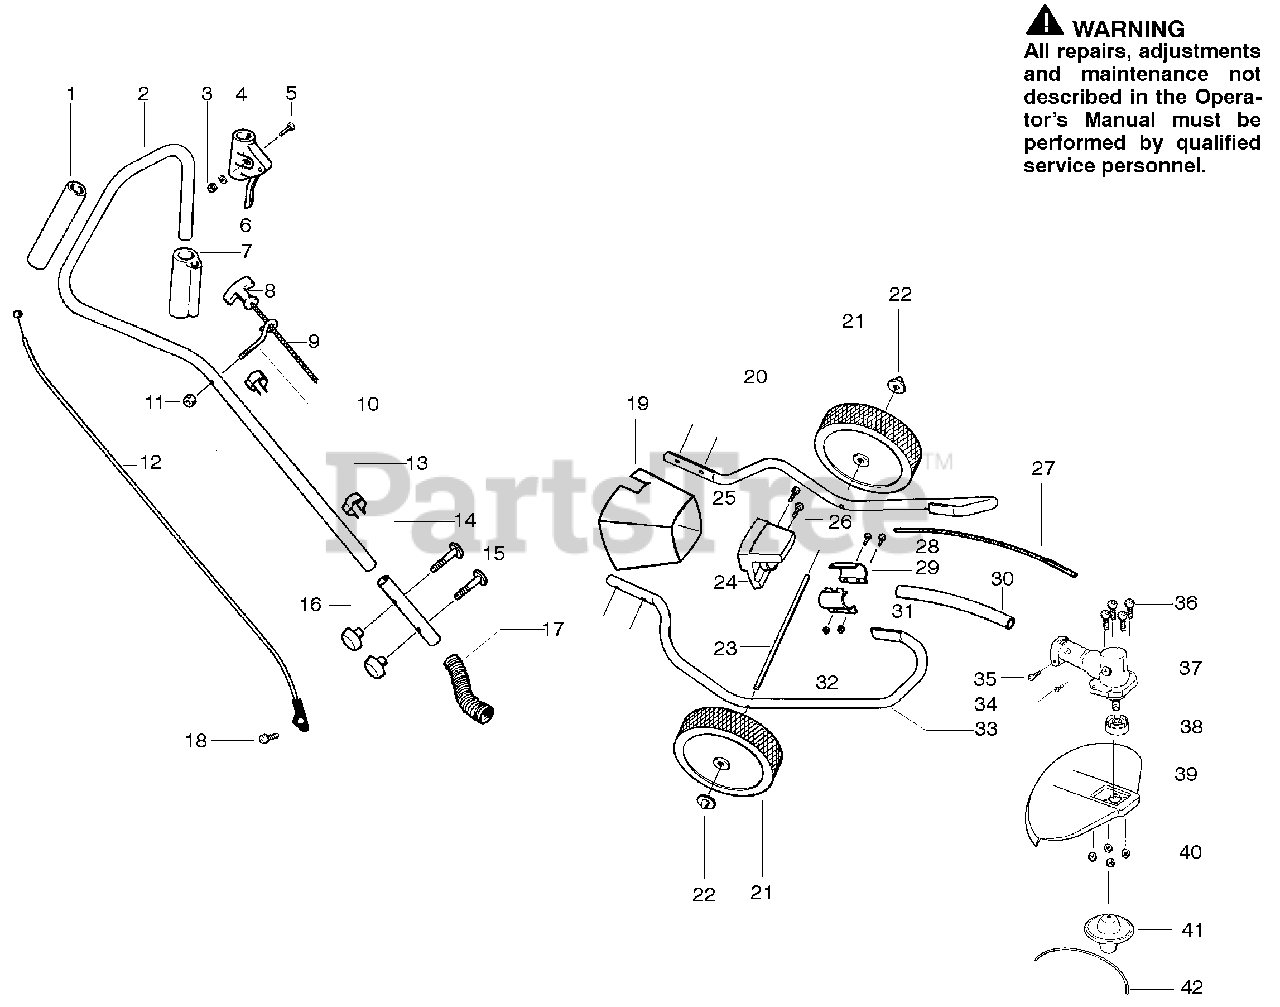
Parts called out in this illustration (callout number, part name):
2	Handle-Upper
4	Assy-Throttle Hsg.
6	Washer-Lock
7	Grip (Closed)
8	Handle-Starter
9	Kit-Rope
10	Guide-Rope
12	Cable-Throttle
13	Clamp-Cable
14	Handle-Lower
17	Air Filter Hose
19	Inlet Screen
20	Frame-Left
21	Kit-Wheel
22	Push Nut
23	Axle 3.75"
24	Assy-Front Retainer
27	FlexShaft (Type 1 & 2)
28	Screw
29	Clamp-Left
30	Assy-Driveshaft
31	Clamp-Right
33	Frame-Right
37	Kit-Gearbox
38	Kit-Dust Cup
41	Assy-Cutting Head w/Line
42	Line (12PK)
42	Operator Manual (Type 1 & 2 )
